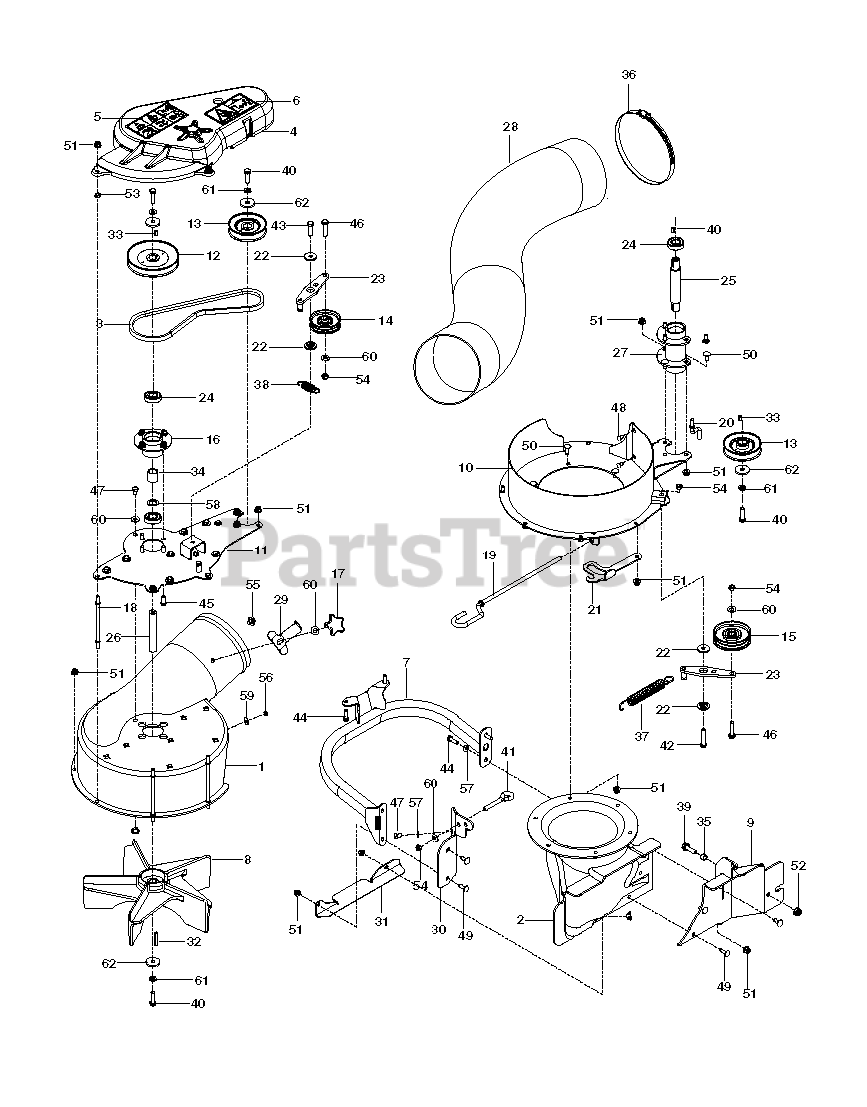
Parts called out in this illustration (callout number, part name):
1	HOUSING, IMPELLER
2	HOUSING, BLOWER
3	BELT-TRANS
4	SHIELD, TOP BELT, W/DECALS
5	DECAL, EURO WARNING
6	EURO DECAL, IMPELLER
7	GUARD, RUB, BLK
8	IMPELLER, WELDMENT
9	MOUNT.REAR.COLLECTION.BLACK
10	LINER BLOWER BLK
11	WELDMENT, TOP PLATE, BLK
13	PULLEY, DRIVE
15	PULLEY, IDLER, BACKSIDE, 3.25"
16	HUB, BEARING
17	KNOB, 5/16-18 X 1/2
18	PIN, RETENTION
19	PIN, MOUNT
20	KEEPER, BELT
21	LATCH, PIN, BLK
22	BUSHING, BRAKE
23	WELDMENT, IDLER, BLK
25	SHAFT, SPINDLE
26	SHAFT, IMPELLER
27	WELDMENT, SPINDLE TUBE
28	HOSE 7 X 60 CLEAR
29	BRACKET, RETAINER, BLK
30	BRACKET, MOUNT, FT-BLK
31	BRACKET, DIVERTER BLK
32	KEY-SQ. 3/16 X 1 1/2
33	KEY, 3/16 X 1/2
35	SPACER,391"ID.375",L.078",WALL
36	CLAMP, HOSE
37	SPRING, DECK DRIVE
38	SPRING, IDLER
39	HHFS 3/8-16 X 1.25 GD 5
40	BOLT, HEX 3/8-24 X 1.25 GR 8
42	BOLT, HCS 3/8-16X1-3/4
43	HCS 3/8C X 1 1/4 GR5
44	HCS 5/16C X 1
45	HCS 5/16C X 3/4
46	HCS 3/8C X 1 1/2
47	HCS 5/16-18 X 1/2 GR 5 ZD
48	RHSSNB, 1/4-20X5/8
49	RHSNB 5/16C X 1
50	BOLT 5/16C X 3/4" CARRIAGE
51	5/16-18 NYLOC FLANGE NUT
52	NUT 3/8-16 HEX FLG NYLOC ZD
53	NUT 5/16-18 HEX JAM ZD
54	NUT HEX 3/8-16 NYLON, THIN
55	NUT 5/16-18 TEE
56	JAM NUT 1/4C (2 2 PW01)
57	FLAT WASHER 5/16 SAE
58	WASHER .787 X 1.125 X .06
59	WASHER 1/4 FLAT
60	WASHER 3/8 SAE FLAT
61	SLW 3/8 STD
62	WASHER, HARDENED
